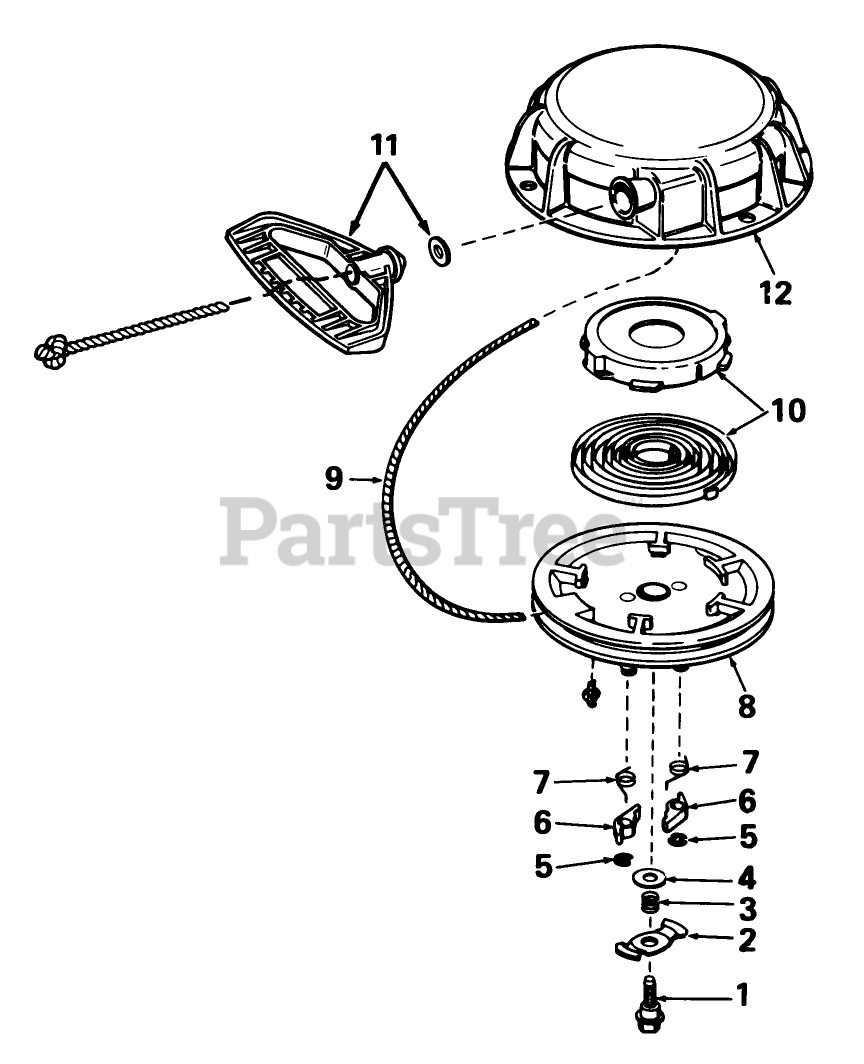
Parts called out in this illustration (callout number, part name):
1	Screw, Center
2	Cam, Dog
3	Spring, Brake
4	Washer, Brake
5	Ring, Retainer
7	Spring, Dog
8	Pulley
9	Rope-Starter
10	Spring Keeper Assy.
11	Handle-Starter, Mitten Grip
12	Housing Assy., Starter
